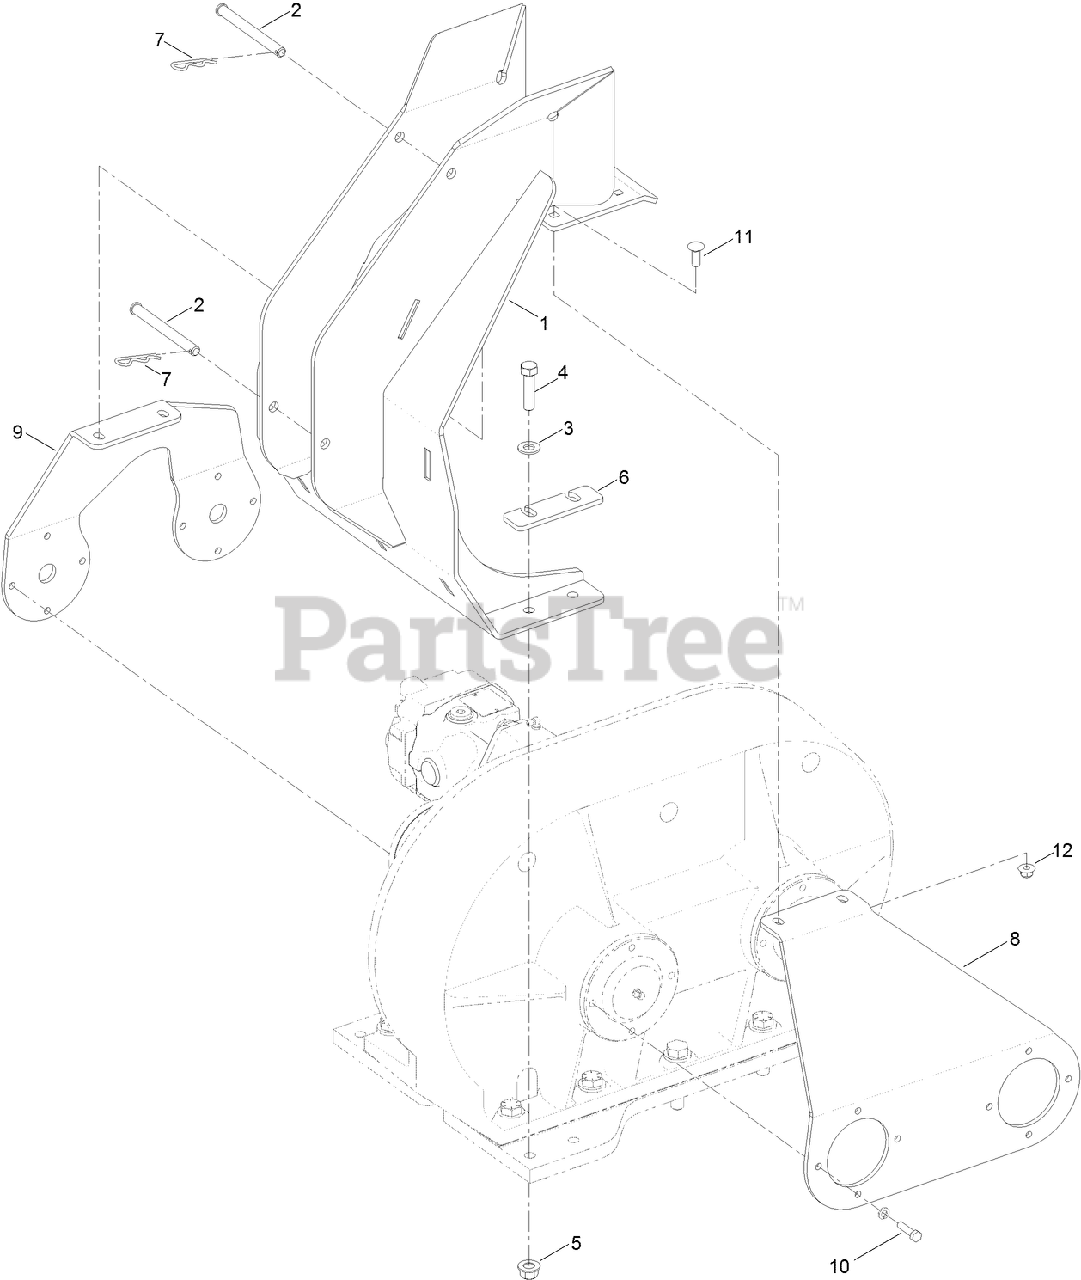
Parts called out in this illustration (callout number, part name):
1	CABLE GUIDE ASM
2	PIN-CLEVIS
3	WASHER-FLAT
4	SCREW-HH
5	NUT-LOCK
6	PLATE-SPACER
7	PIN-HAIR
8	PLATE-CHUTE, RIGHT
9	PLATE-CHUTE, LEFT
10	SCREW-HH
11	SCREW-CARR
12	NUT-HF, NI
